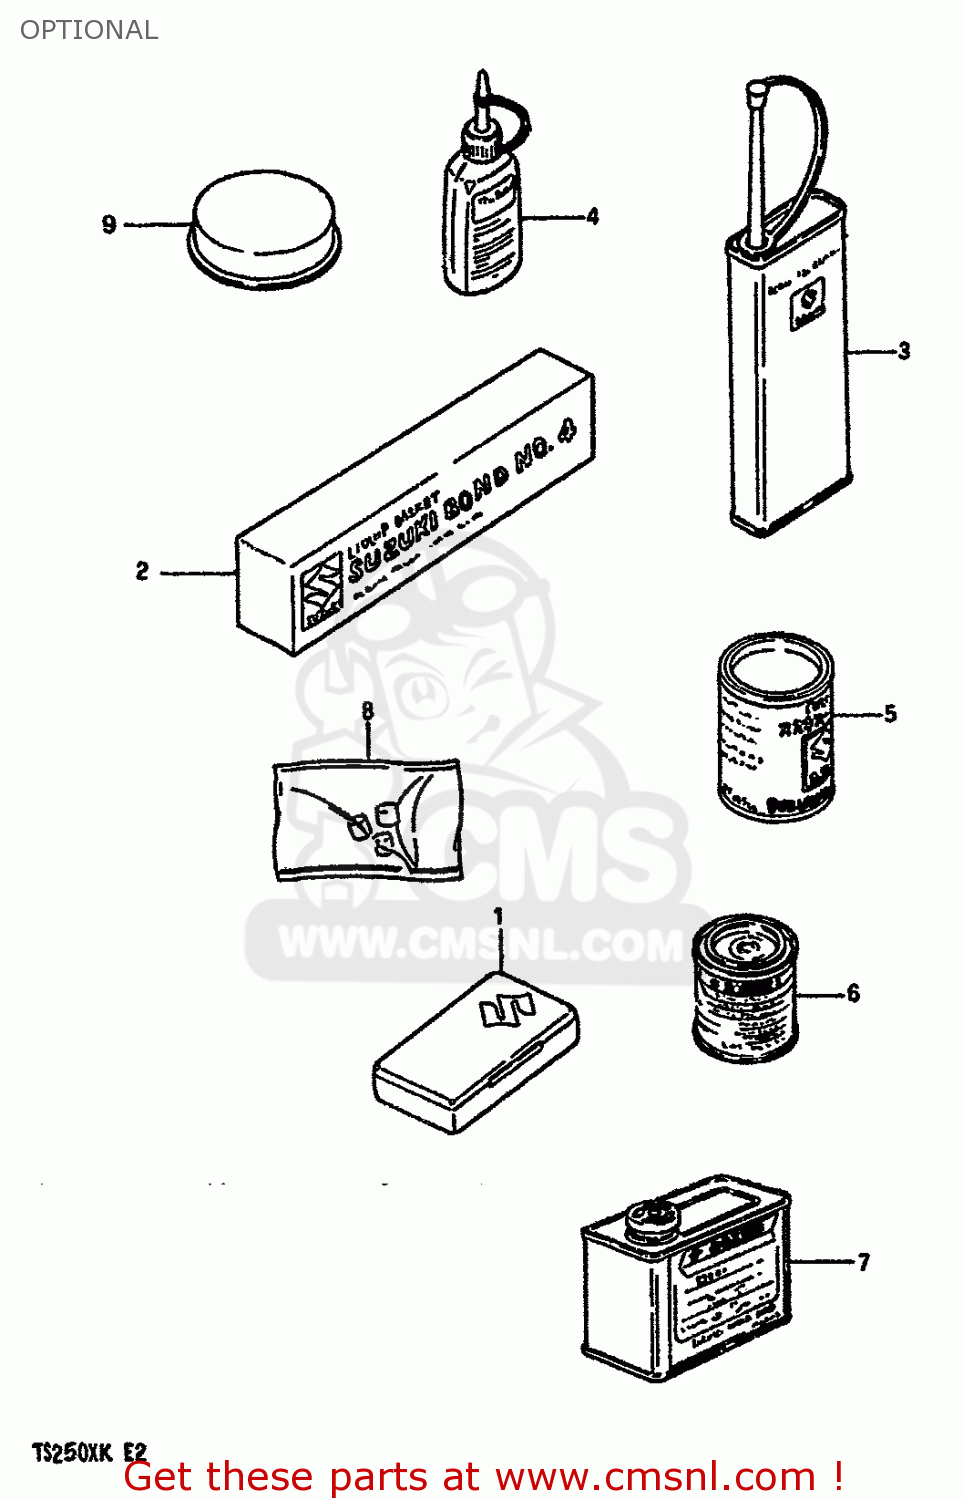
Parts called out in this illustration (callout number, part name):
1	TUBE REPARING TOOL
2	BOND 1104
3	THREAD LOCK NO.1401 CLEAR 200G
4	THREAD LOCK NO
5	GREASE(C)EP2 LITHIUM 150G
6	PAINT,BLACK
7	PAINT (BLACK)
8	ANTI-LEAK ADDITIVE
9	GREASE,PBC FOR BRK PAD 20G
